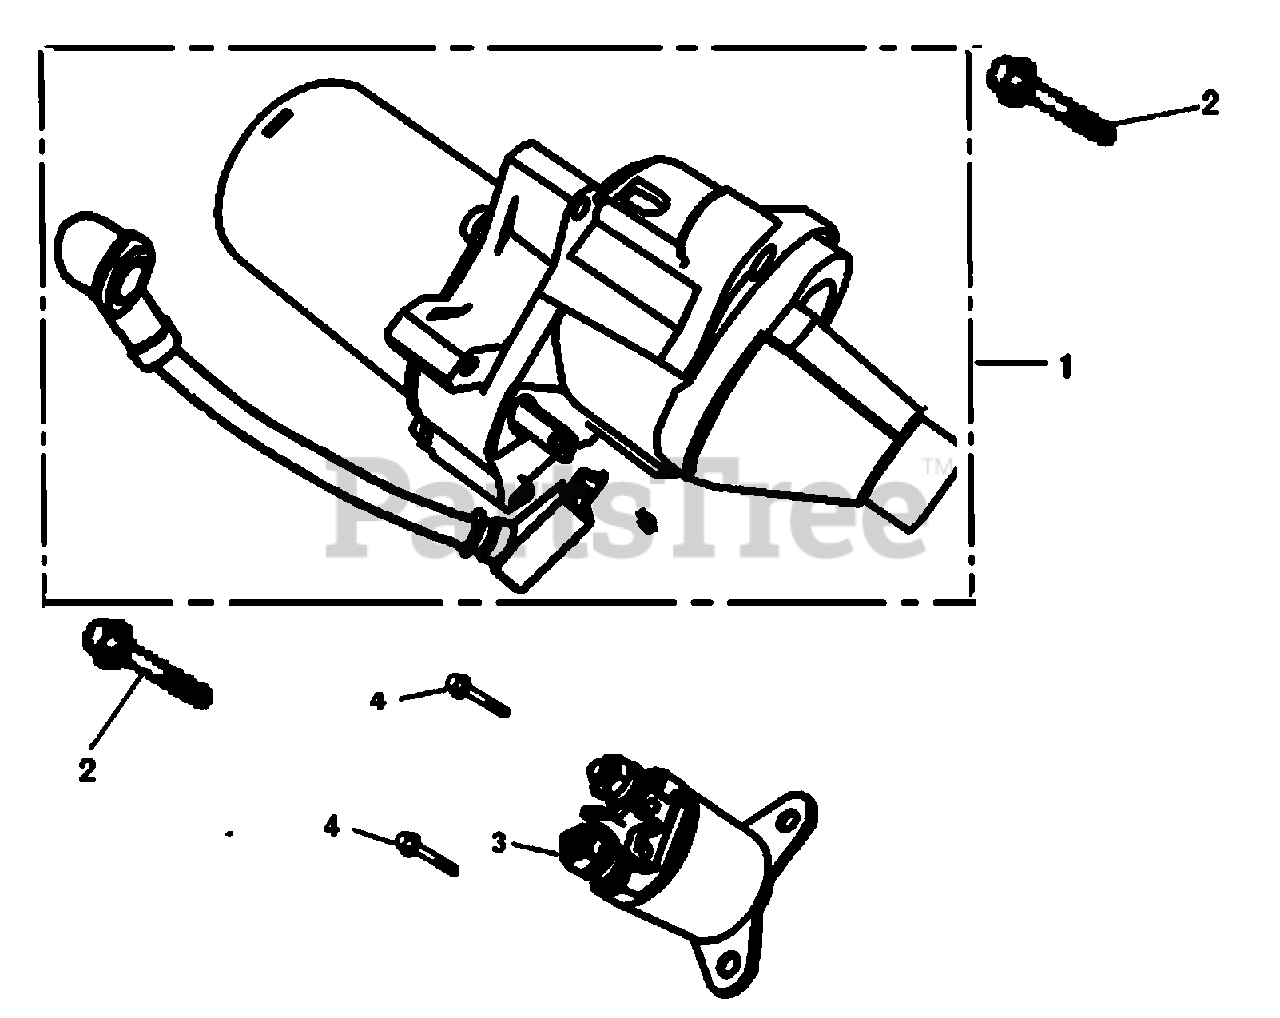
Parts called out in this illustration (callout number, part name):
1	STARTER MOTOR
2	BOLT, FLANGE,
3	CONTACTOR ASSY.
4	BOLT-WASHER
